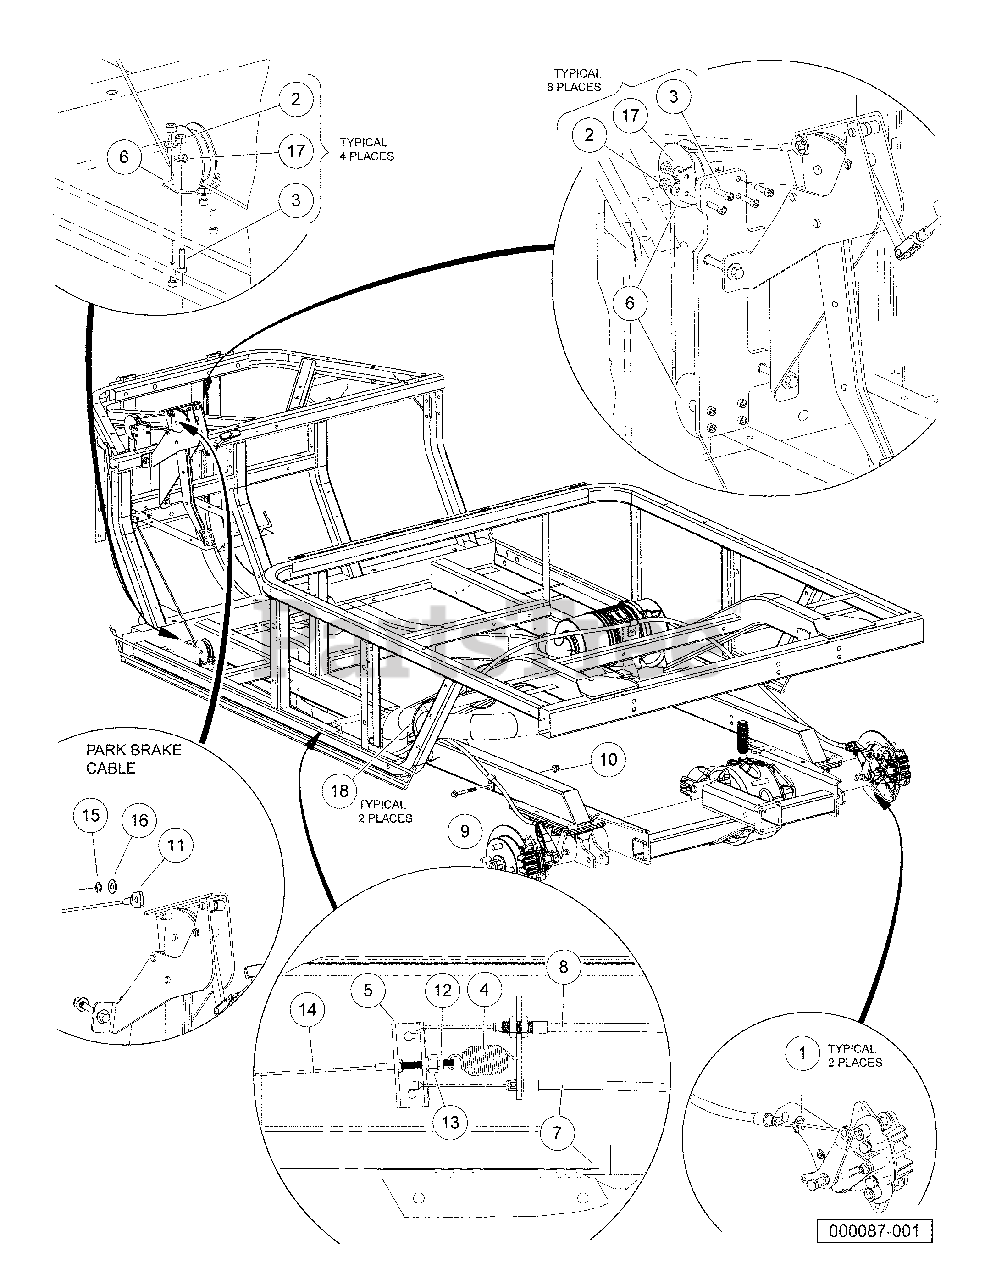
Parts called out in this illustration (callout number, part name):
1	E-Clip, 1/2
2	Locknut, #10-24 Nylon Insert
3	Screw, #10-24 X 3/4 Socket-Head
4	Spring, Brake Return
5	Equalizer Bracket
6	Pulley, 2-Inch Flat Mount
7	Cable, Brake, Parking, Left
8	Cable, Brake, Parking, Right
9	Bolt Flanged Head, M8 X 1.25 X 65
10	Lock Nut, Flg M8 X 1.25 Nylon
11	Brake Cable, Park, Kit, Front
12	Nut, 5/16-24 Hex
13	Nut, 5/16-24 Hex Cone
14	Cable, Brake, Parking, Front
15	Ring, Retaining, External, 9mm
16	Washer, 5/16 Type A Flat
17	Washer, #10 Type A Flat
18	Tie Wrap, 11" Nylon
